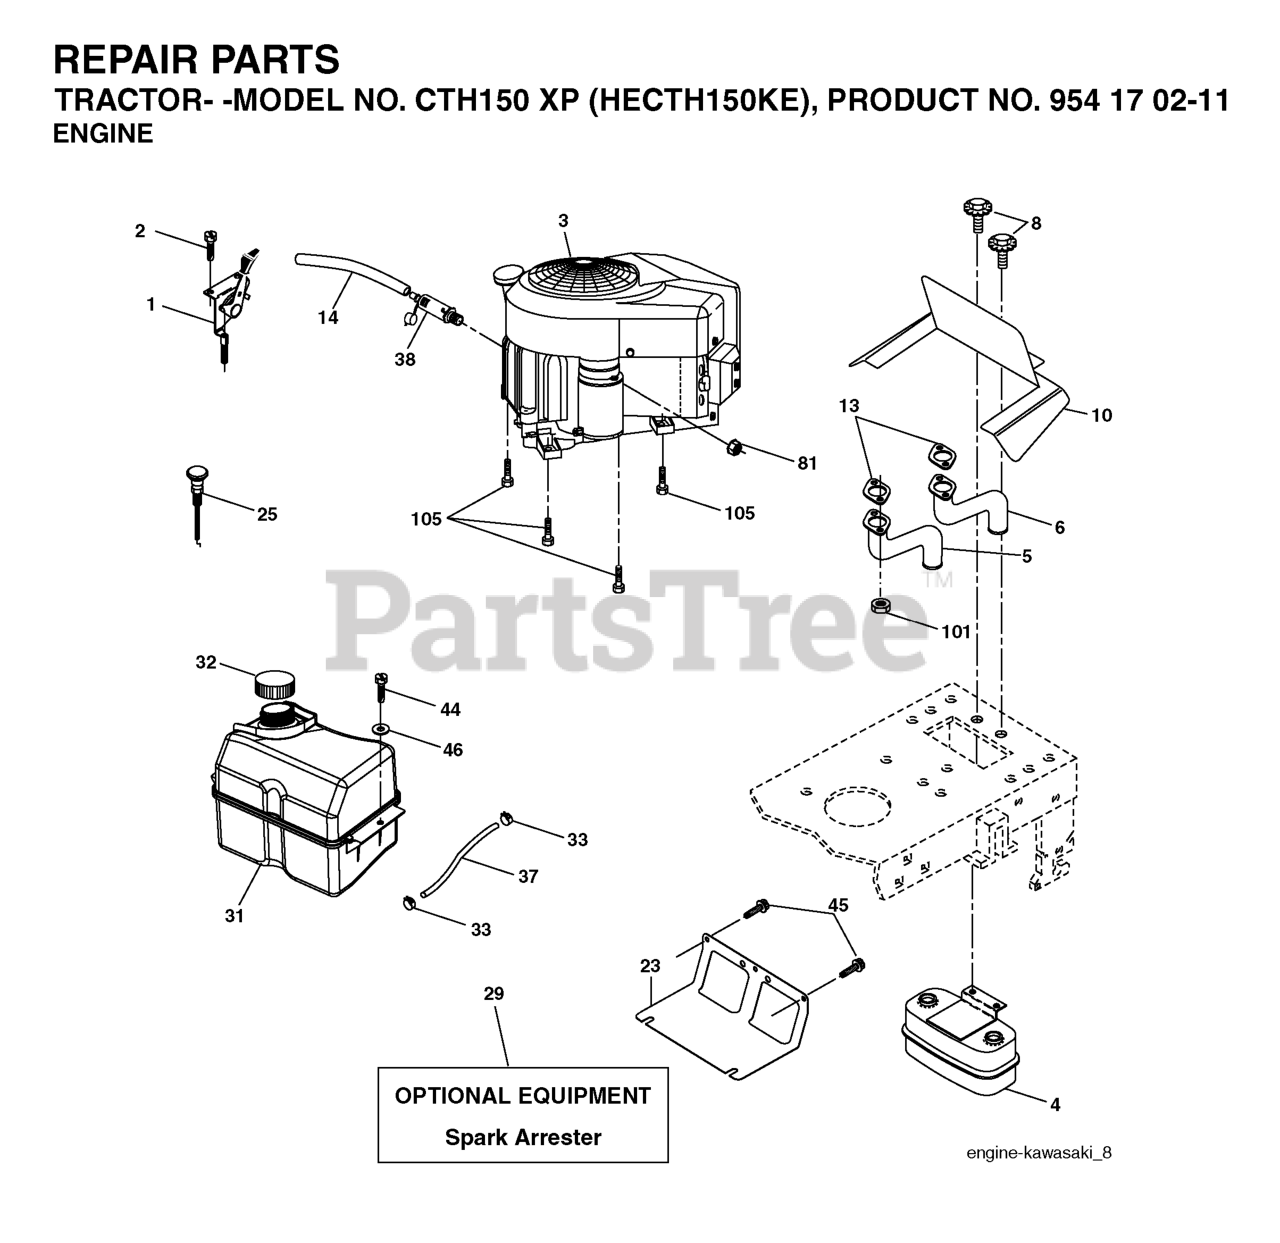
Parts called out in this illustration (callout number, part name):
1	CONTROL, THROTTLE
2	SCREW
4	MUFFLER.TWIN.CYL.LOW.TONE
5	EXHAUST TUBE LH KAWI
6	EXHAUST TUBE RH KAWI
8	BOLT.5/16-18UNCX3/4 W/SEMS.BLK
10	RP SHIELD HEAT MUFFLER
14	TUBE, DRAIN OIL ASM.
23	SHIELD.BROWNING.DBR.GUARD
29	KIT.SPARK ARRESTOR 794945 B&S
31	FUEL TANK
32	FUEL CAP
33	HOSE CLAMP
37	LINE.FUEL.20
44	SCREW HEXWSHR 1/4-20X3/4
45	SCREW, 3/8-16X3/4
81	NUT
101	NUT.HEX.FLANGE.TOPLOCK
105	SCREW 3/8-16X1
